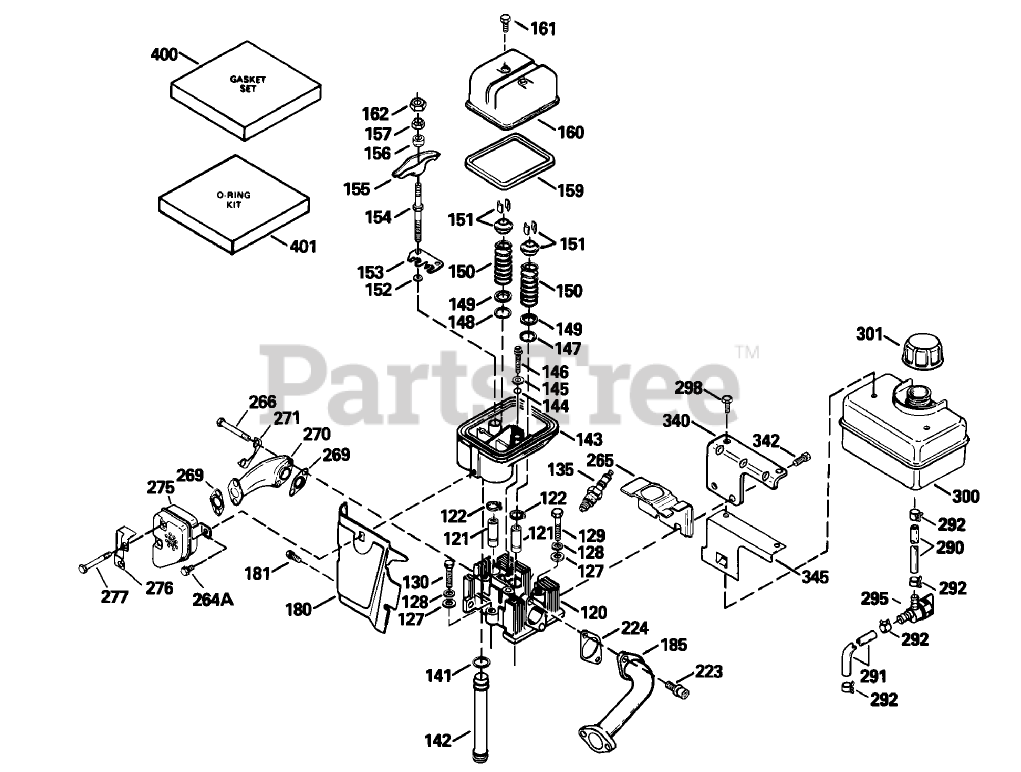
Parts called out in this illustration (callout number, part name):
298	Screw (1/4-15x7/8)
300	Tank-Fuel (Includes 292, 301)
301	Cap-Fuel
340	55073/76/87/90 SNWT
342	Screw (5/16-18 X 7/8)
345	Baffle-Heat
400	Gasket Set
401	O-Ring Kit
